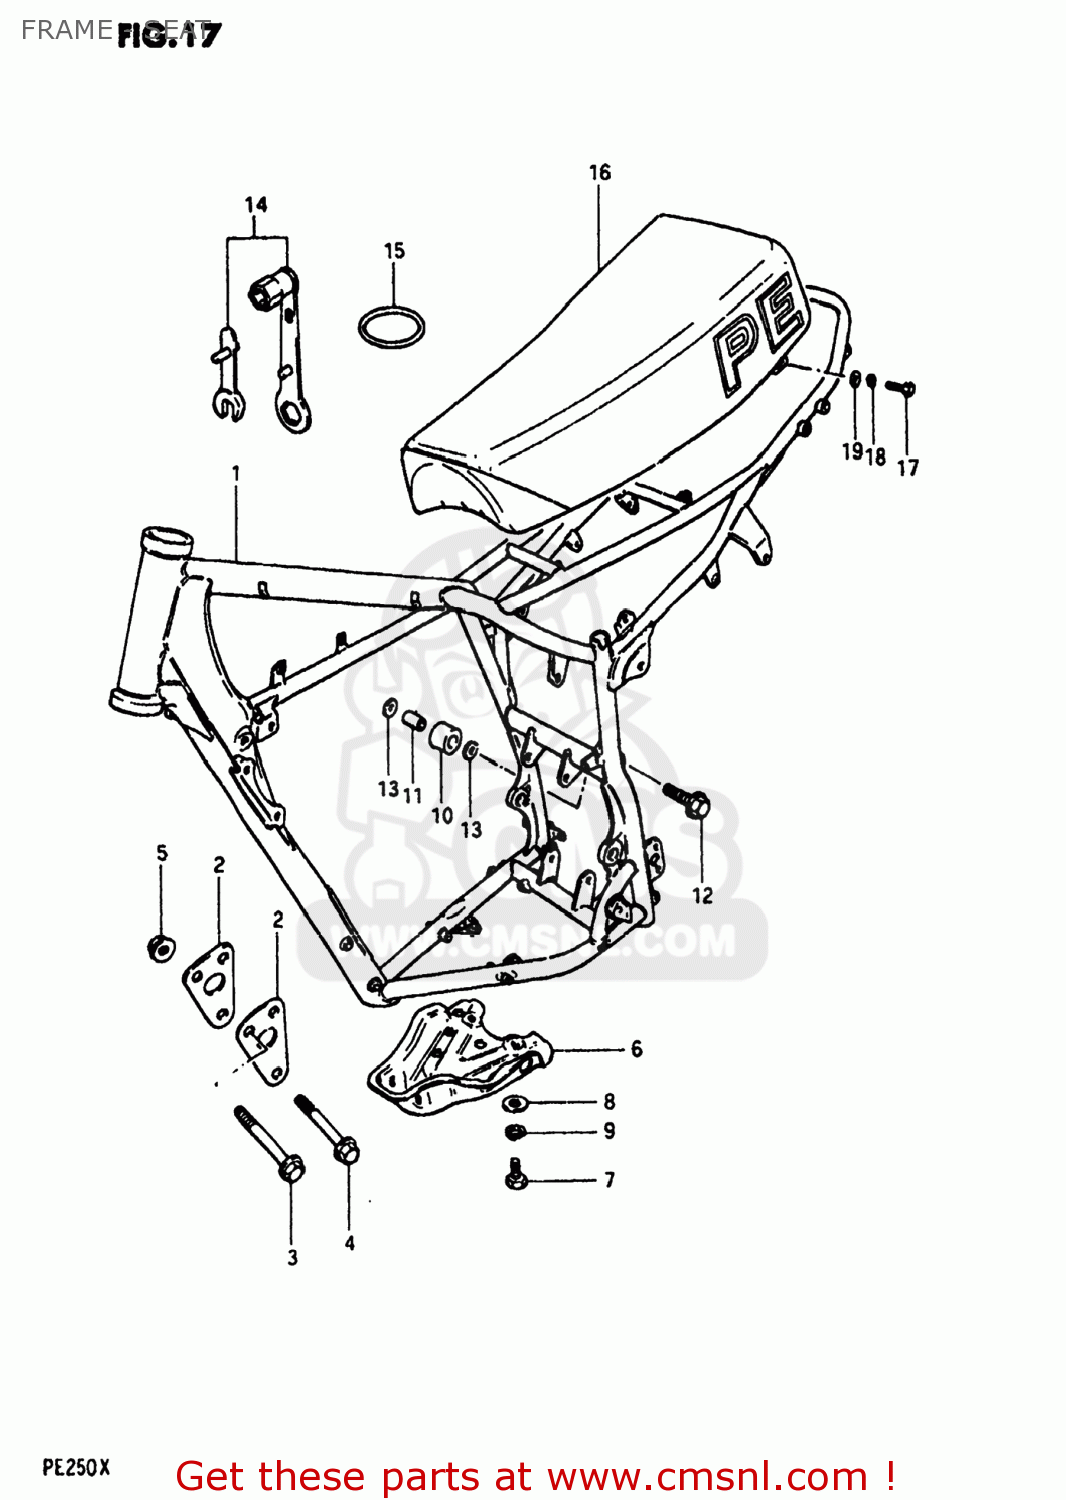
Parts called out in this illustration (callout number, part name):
1	FRAME
2	PLATE,ENGINE MOUNTING
3	BOLT(8X67)
4	BOLT
5	NUT
6	PROTECTOR,ENGINE
7	BOLT
8	WASHER (8.2X20X1.6)
9	LOCK WASHER
10	ROLLER,CHAIN CONTROL
11	SPACER,CHAIN LENGTH ROLLER
12	BOLT(8X45)
13	WASHER
14	SPARK PLUG WRENCH
15	O RING TOOL FITTING
16	SEAT ASSEMBLY
17	BOLT
18	LOCK WASHER
19	WASHER (8.2X20X1.6)
